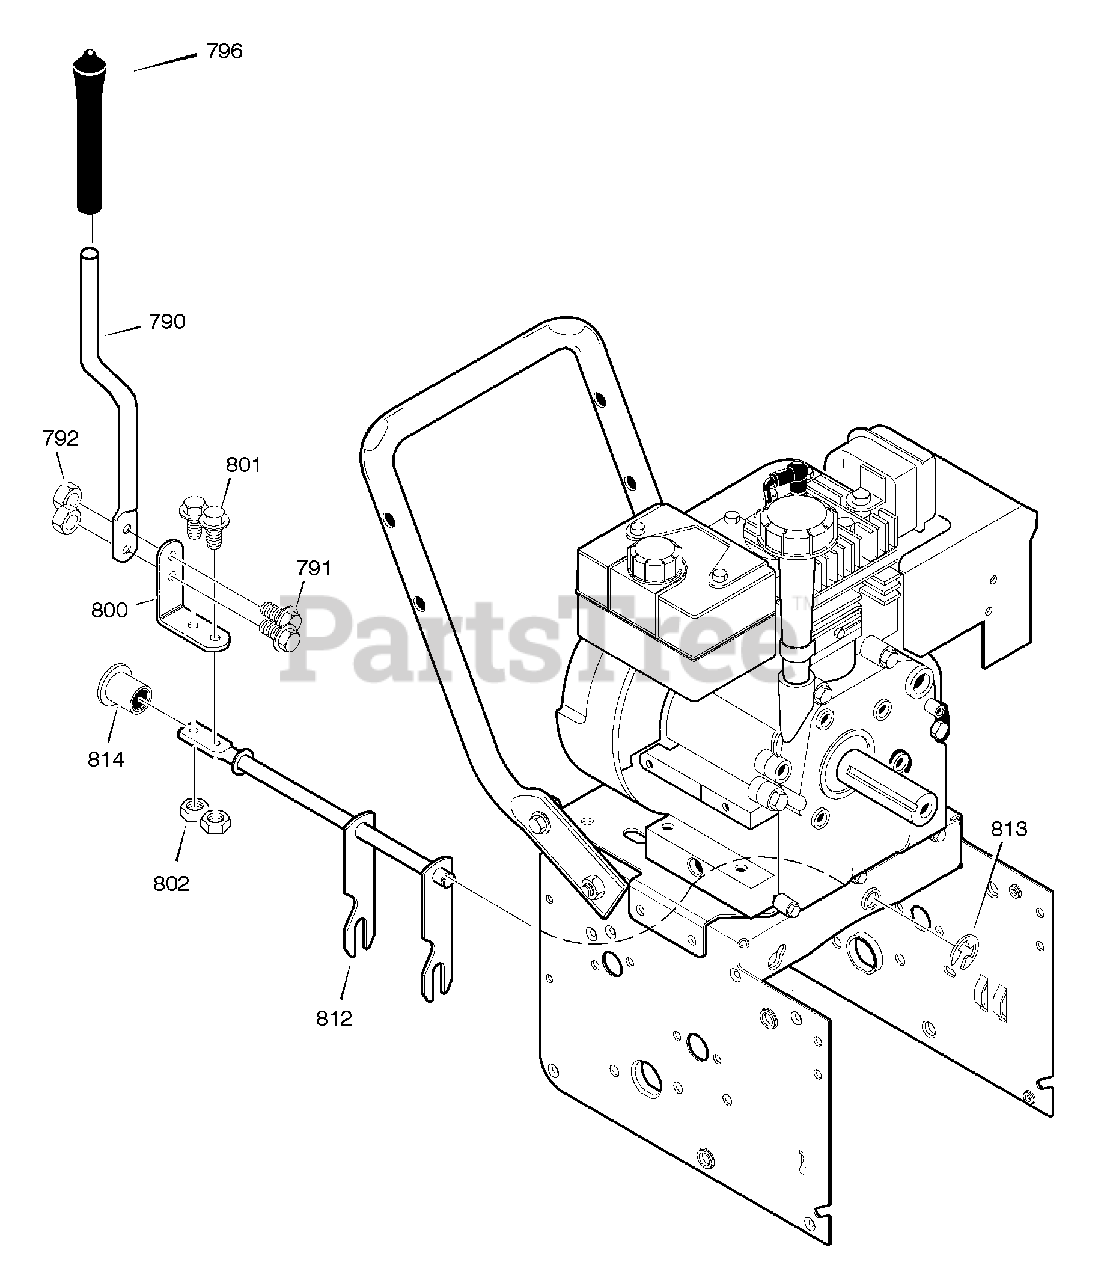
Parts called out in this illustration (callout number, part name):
790	ROD, SHIFT
791	SCREW, 1/4-20X.75
792	NUT, 1/4-20
800	LEVER, SPRING
801	SCREW, 1/4-20X.75
802	NUT, 1/4-20
811	BEARING, FLANGED
812	ROD ASSY., SPEED SELECT
813	RETAINER, RING
